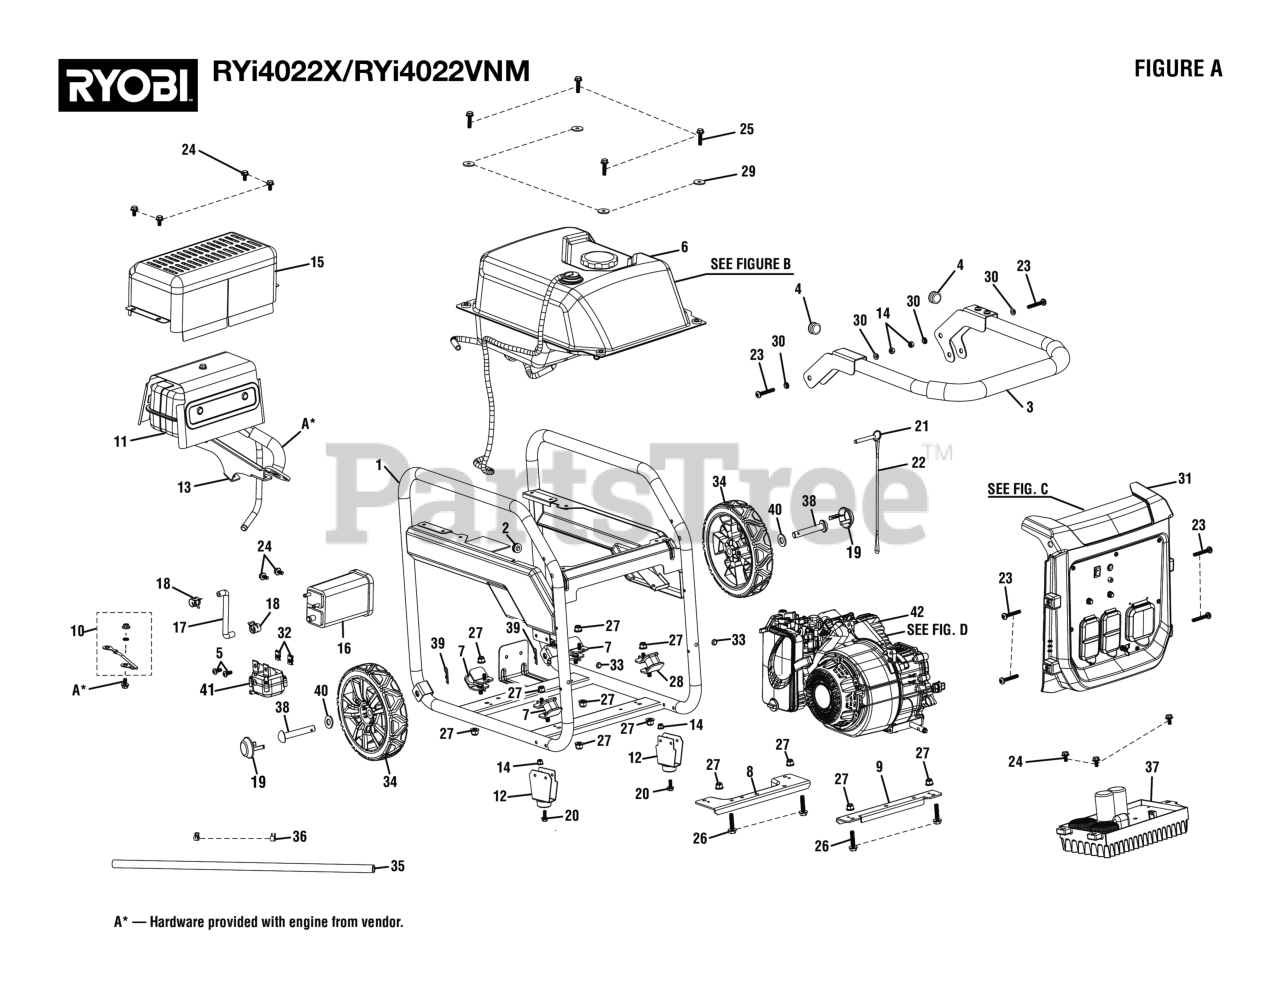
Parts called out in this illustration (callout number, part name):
1	Frame Assembly
2	Grommet
4	Handle End Caps
5	Bolt (M6 x 10 mm, T30 Torx Pan Hd.)
6	Fuel Tank Assembly
7	Isolator (45 Deg, Short)
8	Control Panel Faceplate
9	Bottom Plate (Right)
10	Ground Wire Assembly
12	Foot Assembly
13	Muffler Bracket
14	Lock Nut (M6 x 1 mm)
15	Muffler Heat Shield
16	Carbon Canister (Depurate Q-13-004)
17	Carbon Canister To Airbox Hose.
18	Fuel Clamp (3/8 in)
20	Bolt (M6 x 40 mm, Flange Hex Hd.)
21	Release Pin (5/16 x 2 in.)
22	Lanyard (3/16 in.)
23	Bolt (M6 x 40 mm, T30 Torx Pan Hd.)
24	Flange Bolt (M6 x 12 mm)
25	Flange Bolt (M6 x 25 mm
26	Flange Bolt (M6 x 16 mm, T30 Torx Pan Hd.)
27	Lock Nut (M8 x 1.25 mm, Flange)
28	Isolator (45 Deg, Tall)
30	Shoulder Washer
31	Control Panel Assembly
32	U-Clip (M6)
33	Handle Bumper
34	Front Wheel Assembly
35	Pair Valve Hose
36	Fuel Clamp (3/8 in)
37	Inverter Module
39	Hitch Pin
40	Washer (1/2 in.)
41	CO Detector Assembly
